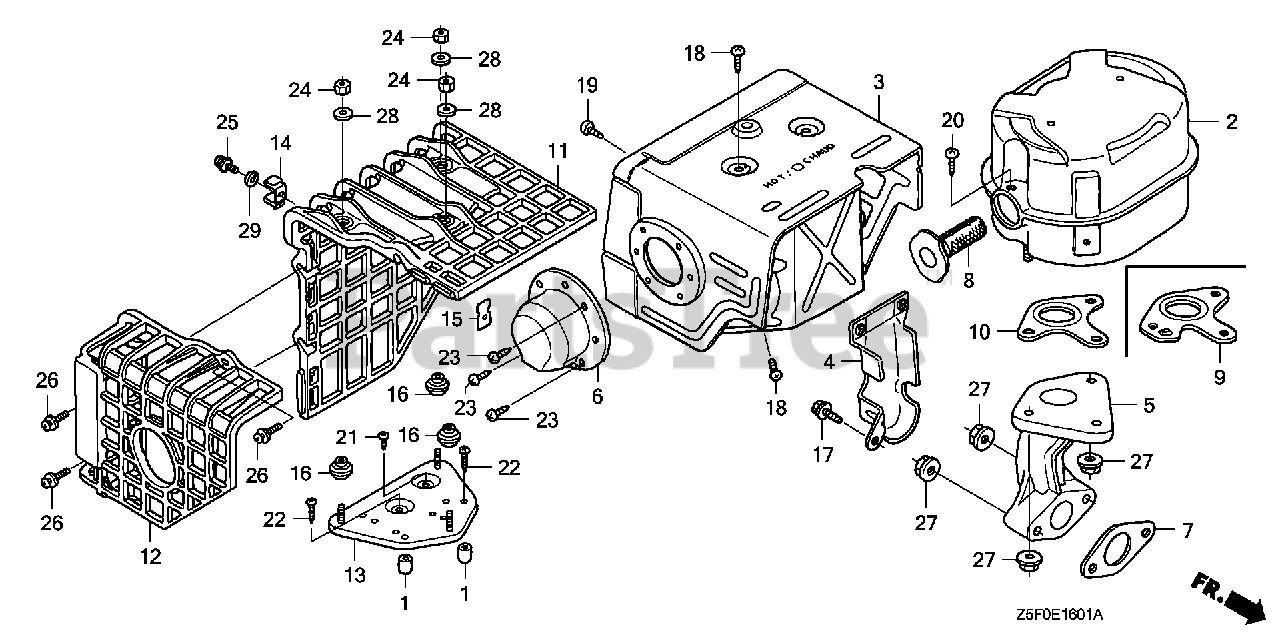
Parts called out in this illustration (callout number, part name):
2	MUFFLER
3	PROTECTOR, MUFFLER (STD)
4	PROTECTOR, EX. PIPE
6	CAP, MUFFLER
7	GASKET, EX. PIPE
8	ARRESTER, SPARK
9	GASKET, MUFFLER (ARRESTER) (NIPPON LEAKLESS)
17	BOLT, FLANGE (6X12) (CT200)
18	SCREW, TAPPING (5X8)
19	SCREW, TAPPING (5X8)
20	SCREW, TAPPING (5X8)
20	SCREW, TAPPING (4X6)
23	SCREW, TAPPING (4X6)
27	NUT, FLANGE (8MM)
